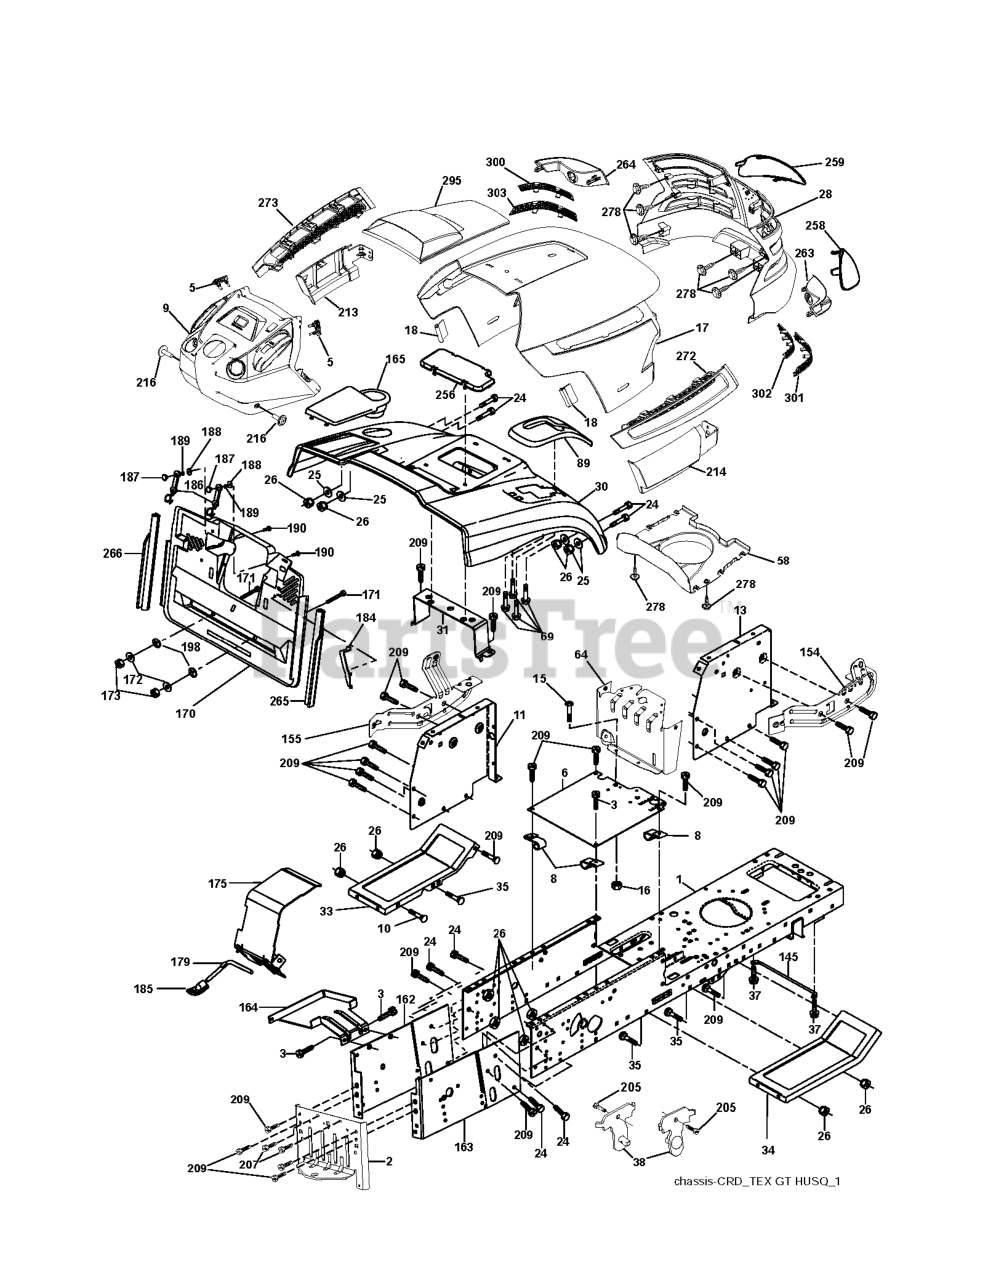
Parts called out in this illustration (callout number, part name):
2	DRAWBAR
3	SCREW 3/8-16X3/4
5	BUMPER DASH
6	PLATE
8	CLIP,INSULATOR
10	BOLT D
11	PANEL DASH LH
13	PANEL DASH RH
15	Screw, Machine, Truss Head 5/16-18 UNC x 3/4
16	NUT
17	HOOD
18	BUMPER.HOOD.TEX.HUSQVARNA
25	WASHER
26	NUT
28	GRILL.ASM.HUSQ.TG/CRD.W/TRIM
30	CONSOLE.CRD.AUTO.GRY
31	BRACKET SUPPORT FENDER
33	FOOTREST PNT LH
34	FOOTREST PNT RH
37	Screw 5/16-18 x 1/2 Hex, Self Tapping 5/16-18 x 1/2
38	BRACKET ASM PIVOT MOWER REAR
58	AIR.DUCT.TEXGT.HUSQ.31
69	SCREW.HI-LO.CONSOLE
89	CONSOLE.CRD.AUTO.GREY.2005
145	ROD.PIVOT.HOOD
162	BRACKET
163	BRACKET EXTEN CHASSIS RH CRD
165	RP.COVER.BATTERY.CRD.GREY
172	WASHER
175	DOOR TRAP
179	ROD PIVOT FBI
184	BRACKET.ACTUATOR.BAGGER.SRD
186	LATCH ASSY
187	WELDNUT
189	LOCKWASHER #10
190	SCREW
207	SCREW, 5/16-18 X 1/2
209	SCREW, 3/8-16X3/4
213	SKIRT.HOOD.SIDE.HUSQ.LH.GREY
214	SKIRT.HOOD.SIDE.HUSQ.RH.GREY
216	SCREW 14-20 X 5/8
256	COVER FENDER CRD
258	LENS.RH.TEX.GT.HUSQ.CL
259	LENS.LH.TEX.GT.HUSQ.CL
263	BEZEL.RH.TEX.GT.HUSQ
264	BEZEL.LH.TEX.GT.HUSQ
265	SEALING
266	SEALING
272	VENT.SIDE.HOOD.HUSQ.RH.GREY
273	VENT.SIDE.HOOD.HUSQ.LH.GRAY
278	SCREW
295	VENT.ASM.TORPHD.HUSQGT.LOGO.CL
300	INSERT.HEX.GRILL.HUSQ.
301	INSERT.HEX.GRILL.HUSQ.GREY
302	INSERT.HEX.GRILL.HUSQ.
303	INSERT.HEX.GRILL.HUSQ.
